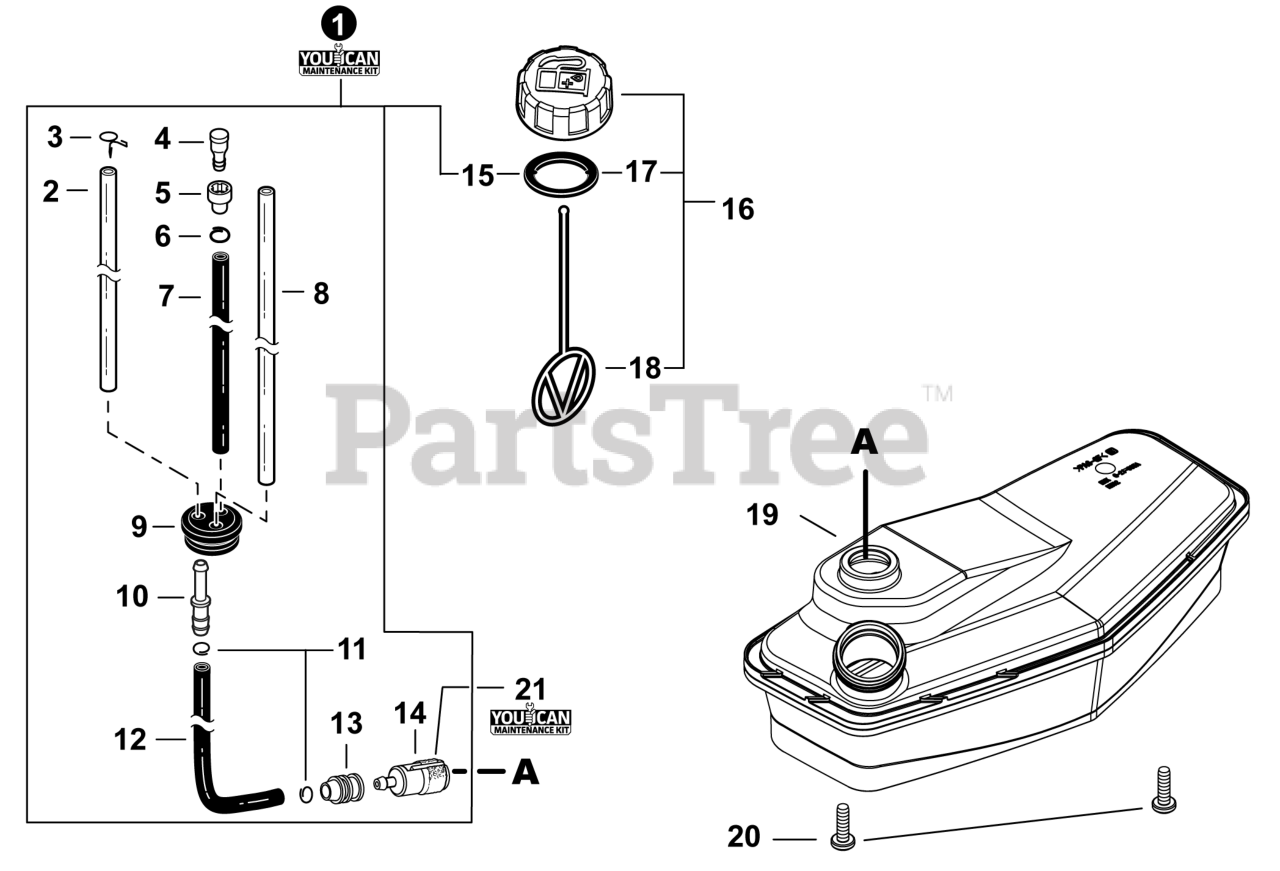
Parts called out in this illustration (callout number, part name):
1	FUEL SYSTEM KIT - YOUCAN™
2	PIPE, FUEL 3.5x6x205 CLEAR
3	CLIP, SPRING 5.2
4	VENT ASSY
5	HOLDER, VENT
6	CLIP 6.5 MM
7	PIPE, FUEL 3x6x40 BLACK
8	PIPE, FUEL 3x6x180 YELLOW
9	GROMMET, FUEL
10	CONNECTOR, PIPE 5x3.5
11	CLIP 6
12	PIPE, FUEL 3x5x165 BLACK
13	BOOT
14	FILTER, FUEL
15	GASKET, FUEL CAP
16	CAP ASSY, FUEL
17	GASKET, FUEL CAP
18	CONNECTOR, CAP L= 123
19	TANK ASSY, FUEL
20	BOLT, TORX 6x20
21	TUNE-UP KIT - YOUCAN™
